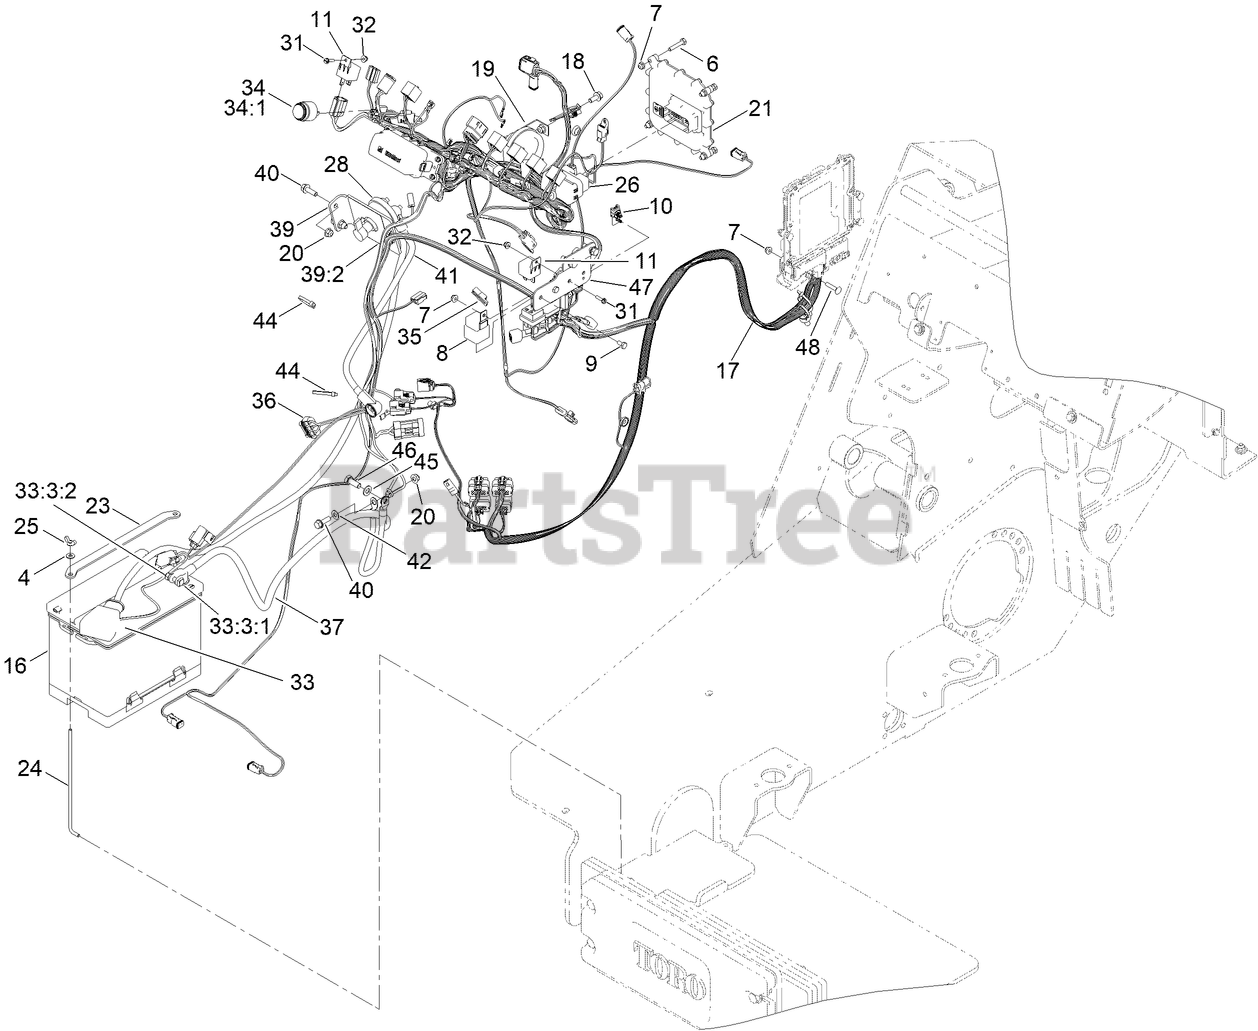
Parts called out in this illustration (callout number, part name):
4	WASHER-FLAT
6	SCREW-HH
7	NUT-HF
8	RELAY-MINI
9	SCREW-HH
10	CLIP-CONNECTOR
11	RELAY
17	HARNESS-WIRE, ENGINE T4
18	SCREW-HHF
19	Horn And Bracket Assembly (Inc. Ref.# 44 45)
20	NUT-HF, NI
21	CONTROLLER
23	STRAP-HOLD DOWN, BATTERY
24	ROD-HOLD DOWN, BATTERY
25	NUT-WING
26	HARNESS-WIRE, TX1300
28	SWITCH-DISCONNECT, MASTER
31	SCREW-HWH
32	NUT-HF
33	CABLE-BATTERY, RD ASM
33:3	BOLT ASM
33:3:1	BOLT-CLAMP, BATTERY
33:3:2	NUT-CLAMP, BATTERY
34	AUDIO ALARM ASM
34:1	NUT-PLASTIC, KNURLED
35	HARNESS-WIRE, FUSIBLE LINK
36	HARNESS-WIRE, FUSIBLE LINK
37	CABLE-BATTERY, NEGATIVE
39	BRACKET-SHUTOFF
39:2	DECAL-BATTERY DISCONNECT
40	SCREW-HHF
41	CABLE-BATTERY, RD ASM
42	WASHER-PLAIN
44	TIE-CABLE
45	WASHER-FLAT
46	SCREW-HH
47	BRACKET-RELAYS
48	SCREW-CARR
